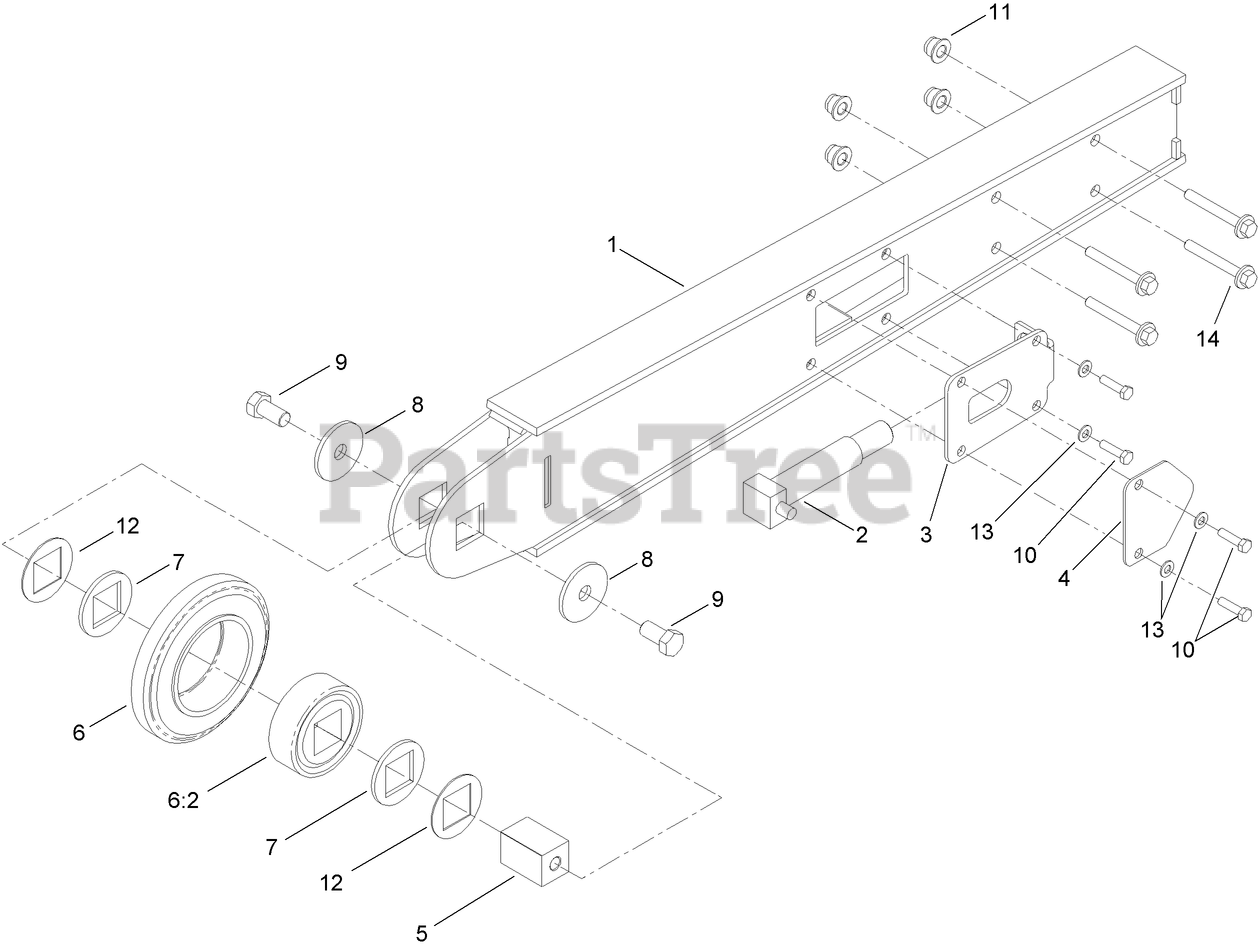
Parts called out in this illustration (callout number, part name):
1	BOOM-ROCK
2	PISTON-ADJ
3	PLATE-PISTON KEEPER
4	PLATE-COVER
5	MOUNT-SHAFT, IDLER
6	IDLER ASM (BOOM END)
6:2	BEARING
7	WASHER
9	SCREW-HH
10	SCREW-HH
11	NUT-HHF, LOCK
13	WASHER-PLAIN
14	SCREW-HHF
